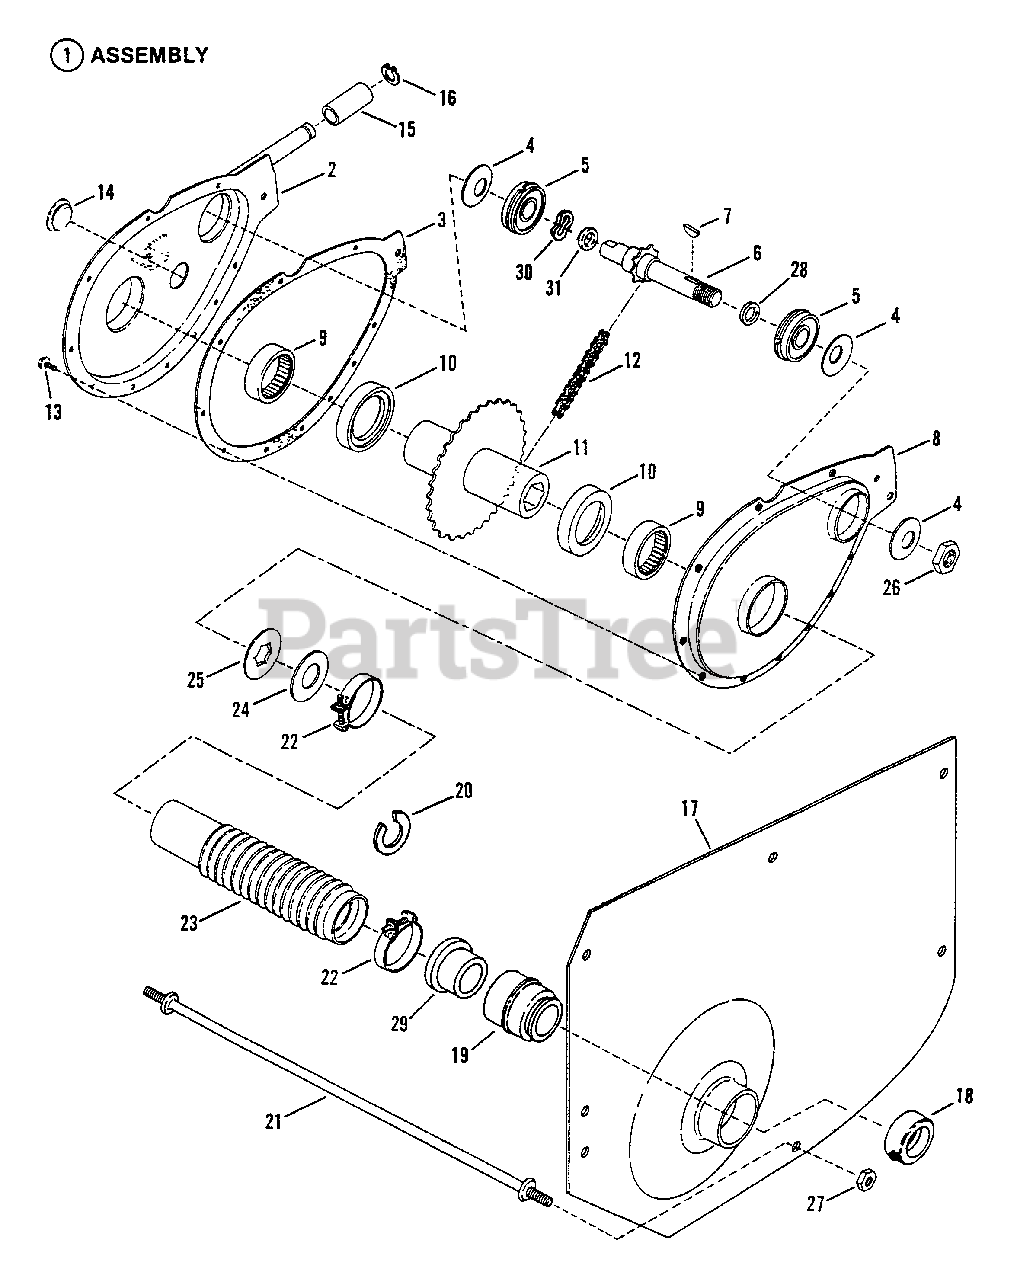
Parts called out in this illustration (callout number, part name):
1	ASSEMBLY, Chain Case
2	CASE, Sprocket
3	GASKET, Case Cover
4	WASHER, Belleville
5	BEARING, Ball
6	SPROCKET & SHAFT
7	KEY, 1/8 x 5/8" Woodruff
8	COVER, Chain Case
9	BEARING, Needle
10	WASHER, Nylon Thrust
11	HUB & SPROCKET
12	CHAIN
13	SCREW, #10-24 x 1/2" Hex Washer Self-Tap (Torx)
14	PLUG, Oil Fill & Check
15	ROLLER
16	RING, Retaining
17	FENDER, Left Hand
18	COLLAR, Lock
19	BEARING, Left Hand Fender
20	WASHER, Shim
21	ROD, Cross-Tie
22	CLAMP, Boot
23	BOOT, Oil Seal
24	WASHER, Thrust Nylon
25	WASHER, Thrust
26	NUT, 5/8-18 Hex Lock
27	NUT, 5/16-24 Hex Flange Lock
28	O-RING
29	SPACER
30	WASHER, Wave
31	WASHER, Shim
